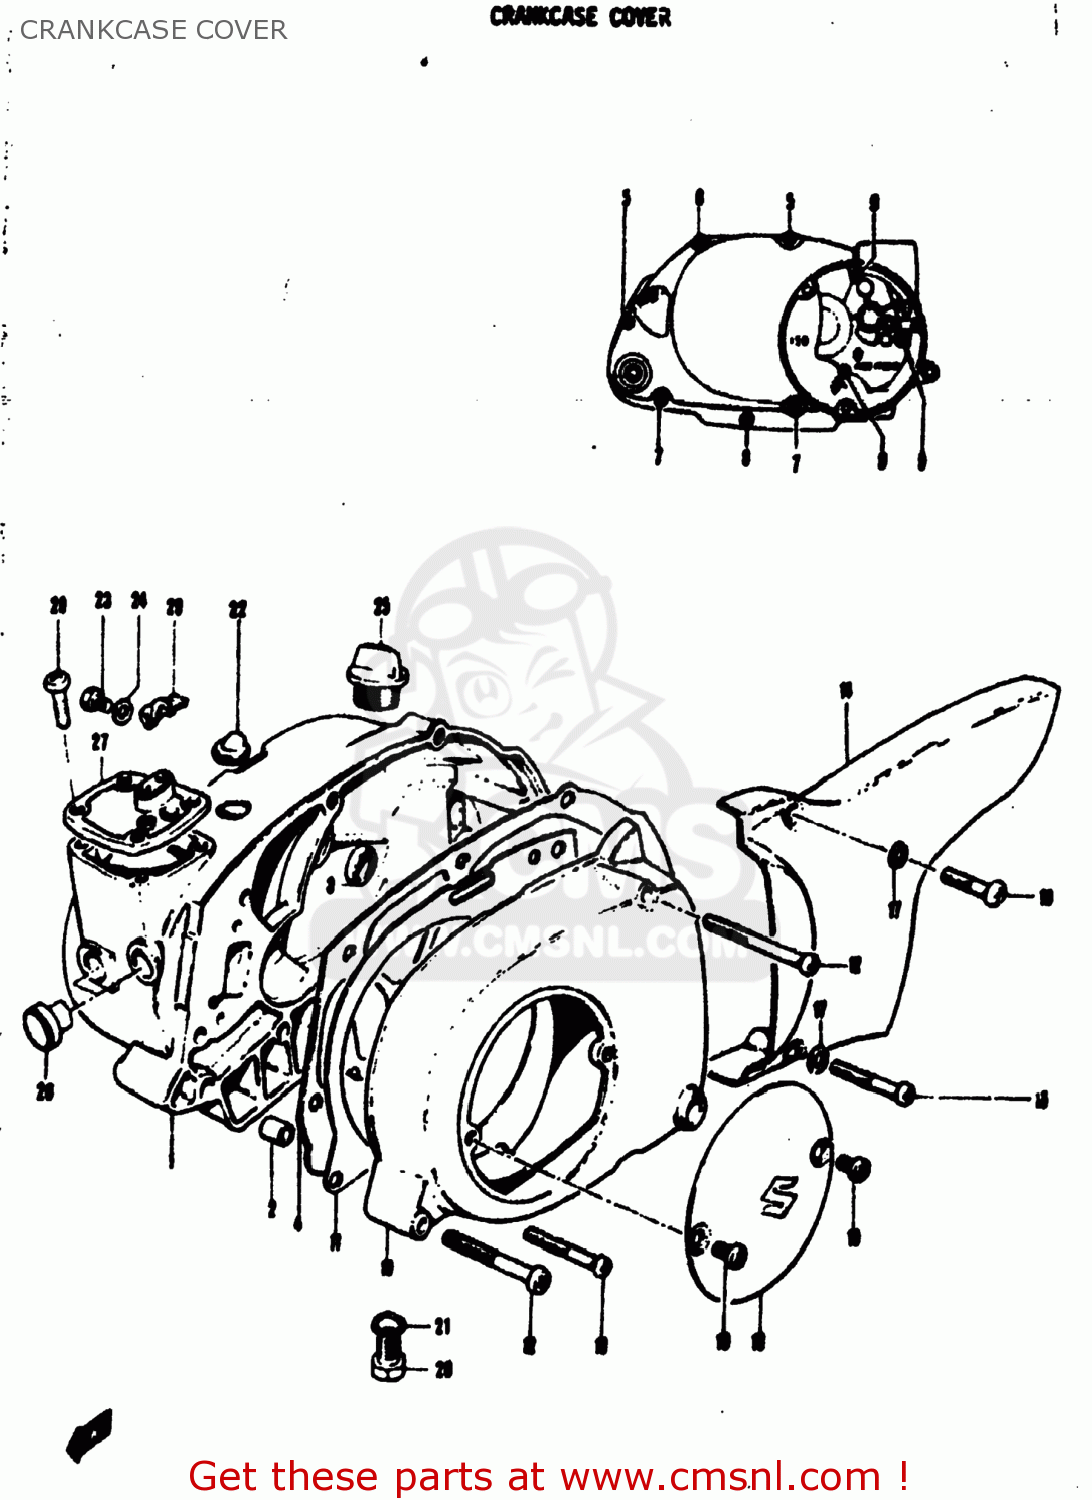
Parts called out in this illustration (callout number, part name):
2	PIN
3	SEAL,OIL (10X17X5)
4	CRANKCASE RH COVER GASKET (MCA)
5	SCREW 6X70
6	SCREW (6X35)
7	SCREW
8	SCREW
9	SCREW
10	COVER,MAGNETO
11	GASKET,MAGNETO COVER
12	SCREW
13	SCREW
14	COVER, ENGINE SPROCKET
15	SCREW (6X45)
16	SCREW
17	WASHER 6MM
18	CAP
19	SCREW
20	PLUG
21	GASKET(13.8X18.8X4.8) (NAS)
22	FUEL PIPE GROMMET
23	SCREW(6X10)
24	GASKET(6.2X11X1) (NAS)
25	PLUG,OIL FILTER
26	Plug
27	COVER,CARBURETOR TOP
28	SCREW
